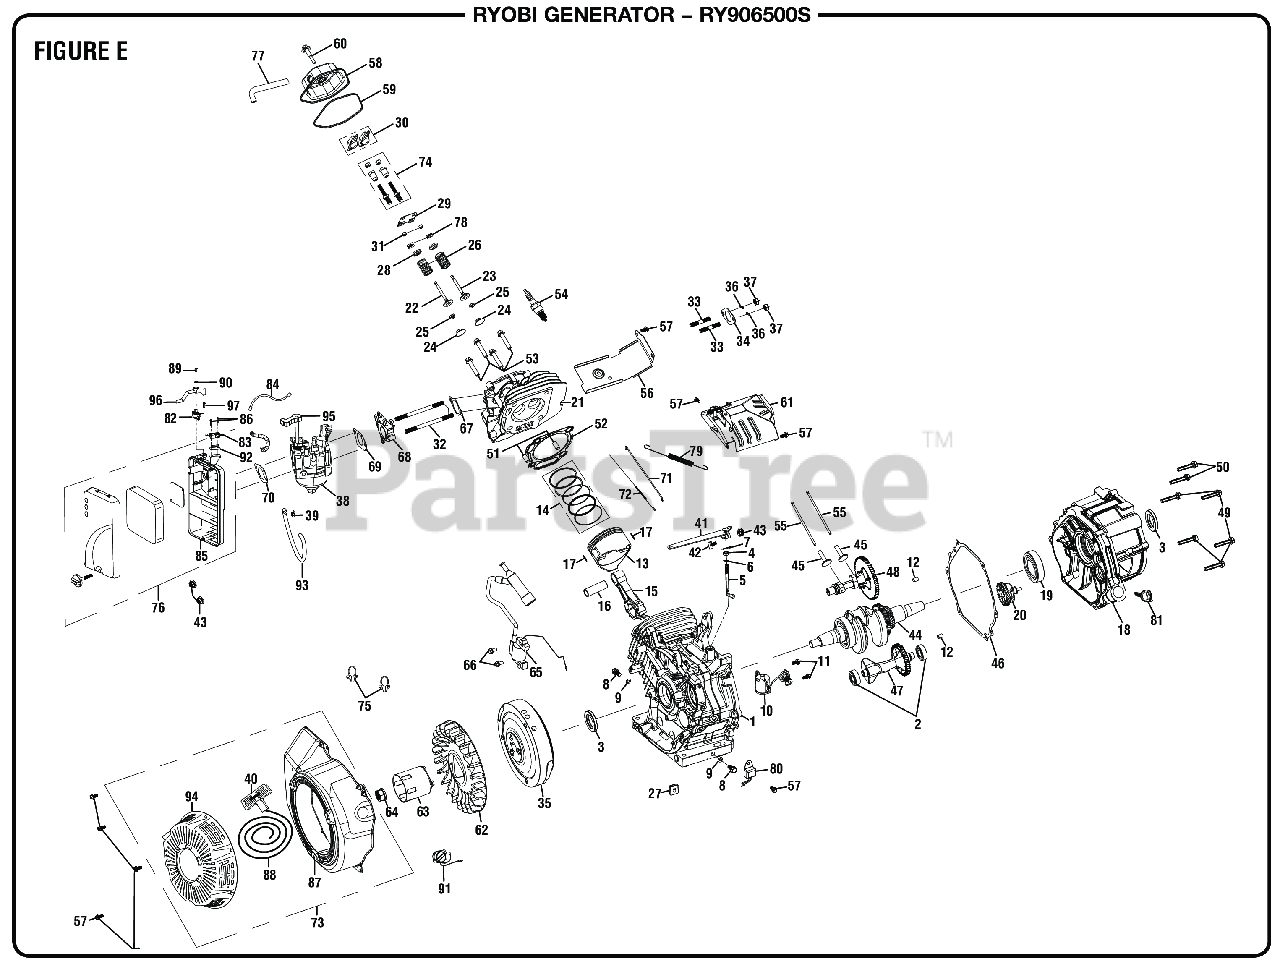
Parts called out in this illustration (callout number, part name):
1	Crankcase
2	Ball Bearing
3	Oil Seal
4	Governor Arm Shaft Seal
5	Governor Arm Shaft
6	Governor Arm Shaft Washer
7	Lock Pin
8	Drain Plug Bolt.
9	Drain Plug Washer
10	Oil Level Switch Assembly
11	Bolt (M6 x 16 mm)
12	Casecover Dowel Pin
14	Piston Scraper Ring Set
15	Connecting Rod Assembly
16	Piston Pin
17	Piston Clip
18	Crankcase Cover Assembly
19	Ball Bearing
20	Governor Assembly
21	Cylinder Head
22	Intake Valve
23	Exhaust Valve
24	Intake Valve Returner
25	Oil Seal Valve
26	Valve Spring
27	Starter Assembly Rubber
28	Exhaust Valve Spring Seat
29	Push Rod Guide Plate
30	Rocker Assembly
32	Stud Bolt
33	Stud Bolt
34	Exhaust Packing
35	Flywheel Assembly
36	Spring Washer
37	Hex Nut (M8)
38	Carburetor Assembly
39	Fuel Line Clip
41	Governor Arm
42	Governor Arm Bolt
43	Hex Nut (M6)
44	Crankshaft Assembly
45	Valve Lifter
46	Casecover Package
47	Balancing Shaft
48	Camshaft Assembly
49	Bolt (M8 x 35 mm)
50	Bolt (M8 x 40 mm)
51	Dowel Pin
52	Cylinder Head Gasket
53	Bolt (M10 x 80 mm)
54	Spark Pulg
55	Push Rod.
57	Bolt (M6 x 12 mm)
58	Cylinder Head Cover Comp
59	Headcover Packing
60	Lock Bolt
61	Upper Shroud Assembly
62	Recoil Starter Fan
63	Starter Pulley
64	Hex Nut (M5)
65	Ignition Coil Assembly
66	Bolt (M6 x 25 mm)
67	Intake Packing
68	Carburetor Insulator
69	Carburetor Packing
70	Carburetor Spacer
71	Governor Rod
72	Throttle Return Spring
73	Recoil Starter Assembly
74	Rocker Arm Adujuster
76	Air Cleaner Assembly
77	Breather Tube
78	Locking Flaps
79	Governor Spring
80	Amplifier
81	Dipstick
82	Fuel Valve
83	Enginge Stop Switch
84	Flameout Wire
85	Air Cleaner Bottom Cover
86	Screw (St 2.9 x 16 mm, Pan Hd)
87	Recoil Starter Assembly
89	Screw (M4 x 10 mm, Phillips Pan Hd.)
91	Switch Assembly
92	Engine Switch Bracket
93	Fuel Hose (330 mm)
94	Recoil cover
95	Choke Lever (Grey)
96	Control Lever (Grey)
97	Screw (M6 x 10 mm, Pan Hd.)
